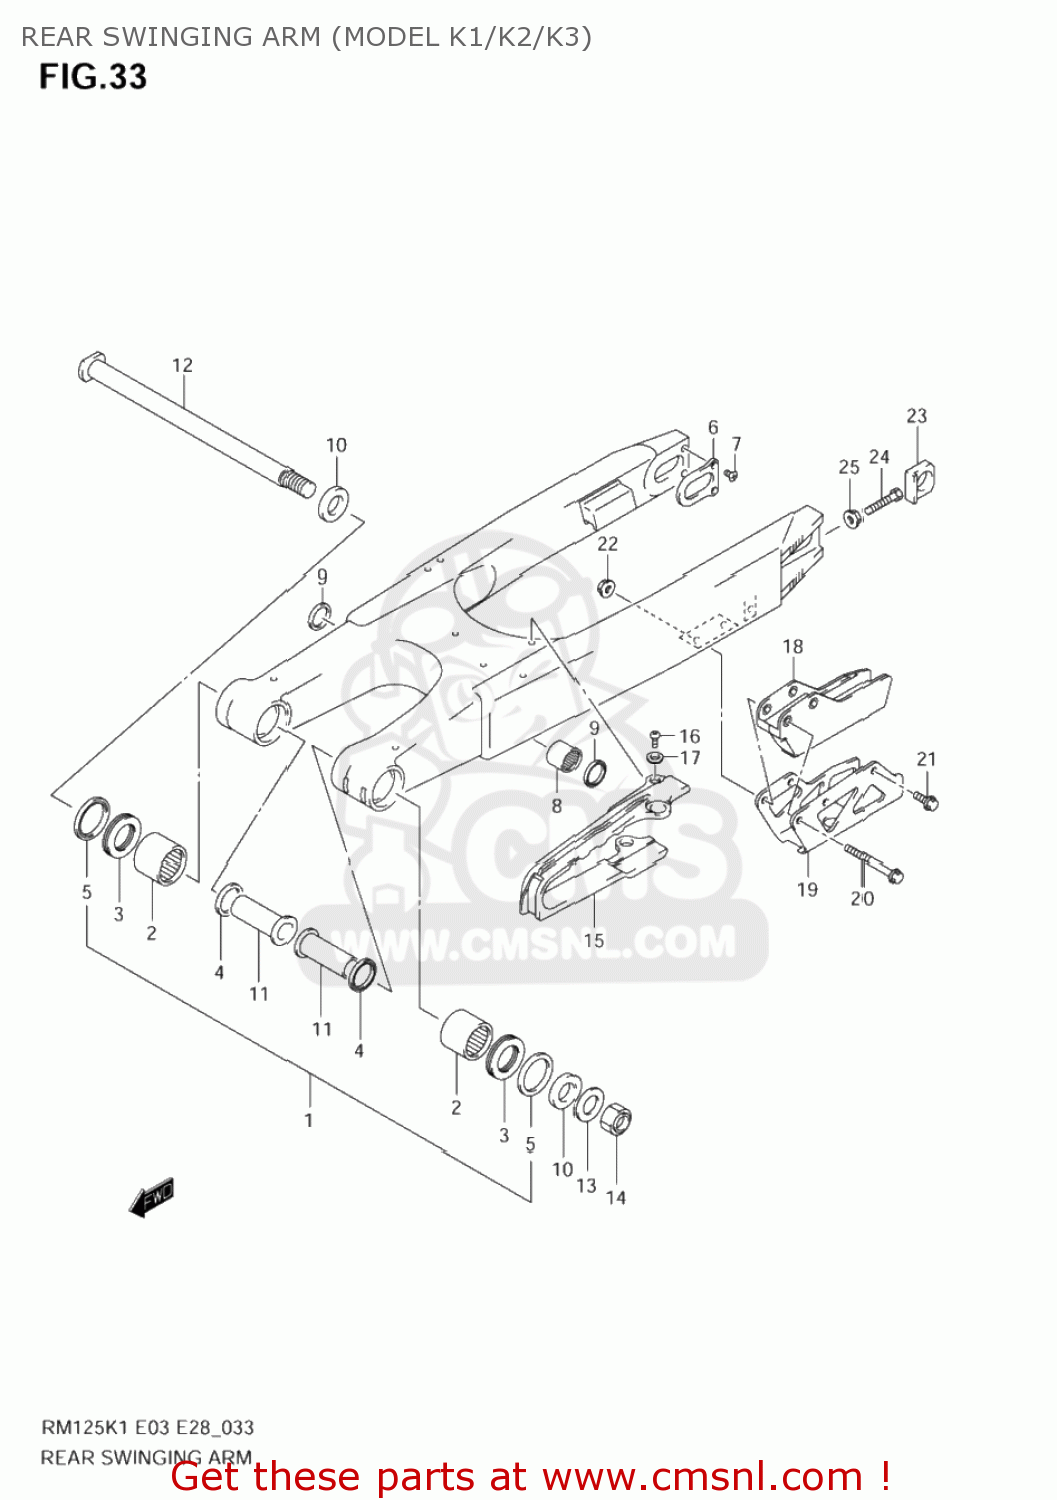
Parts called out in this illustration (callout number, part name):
1	SWINGINGARM ASSY,RR
2	BEARING(22X29X30)
3	BEARING(22X35X2)
4	SEAL,OIL(22X29X4)
5	SEAL,RR SWGARM PIVOT OUTER
6	PLATE,RR SWING ARM RR
7	SCREW,UPPER
8	BEARING(20X27X15)
9	SEAL,CUSHION LEVER DUST
10	SPACER,RR SWGARM PIVOT OUTER
11	SPACER,SWGARM PIVOT INNER
12	SHAFT,RR SWINGINGARM PIVOT
13	WASHER, FIXED DRIVE FACE
14	NUT
15	BUFFER,CHAIN T
16	SCREW
17	WASHER
18	GUIDE,CHAIN
19	PLATE,CHAIN GUIDE
20	BOLT(6X45)
21	BOLT(6X12)
22	NUT
23	WASHER,CHAIN ADJUSTER
24	BOLT(8X50)
25	NUT
